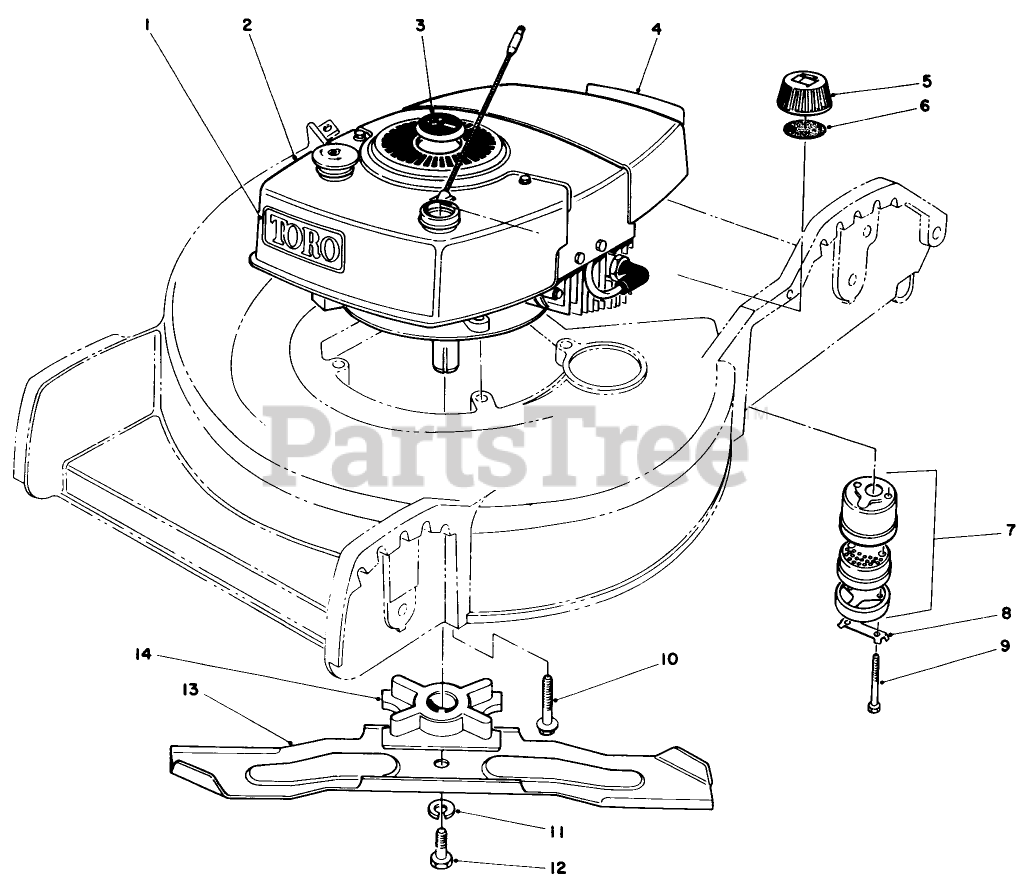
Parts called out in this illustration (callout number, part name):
2	Engine
3	PLUG BUTTON
6	GAS CAP GASKET
7	MUFFLER ASM
8	CLIP - LOCKING
9	SCREW-HH
10	3/8-16 X 2 CAPSCREW
11	WASHER-LOCK
12	SCREW-HH
14	BLADE RETAINER
